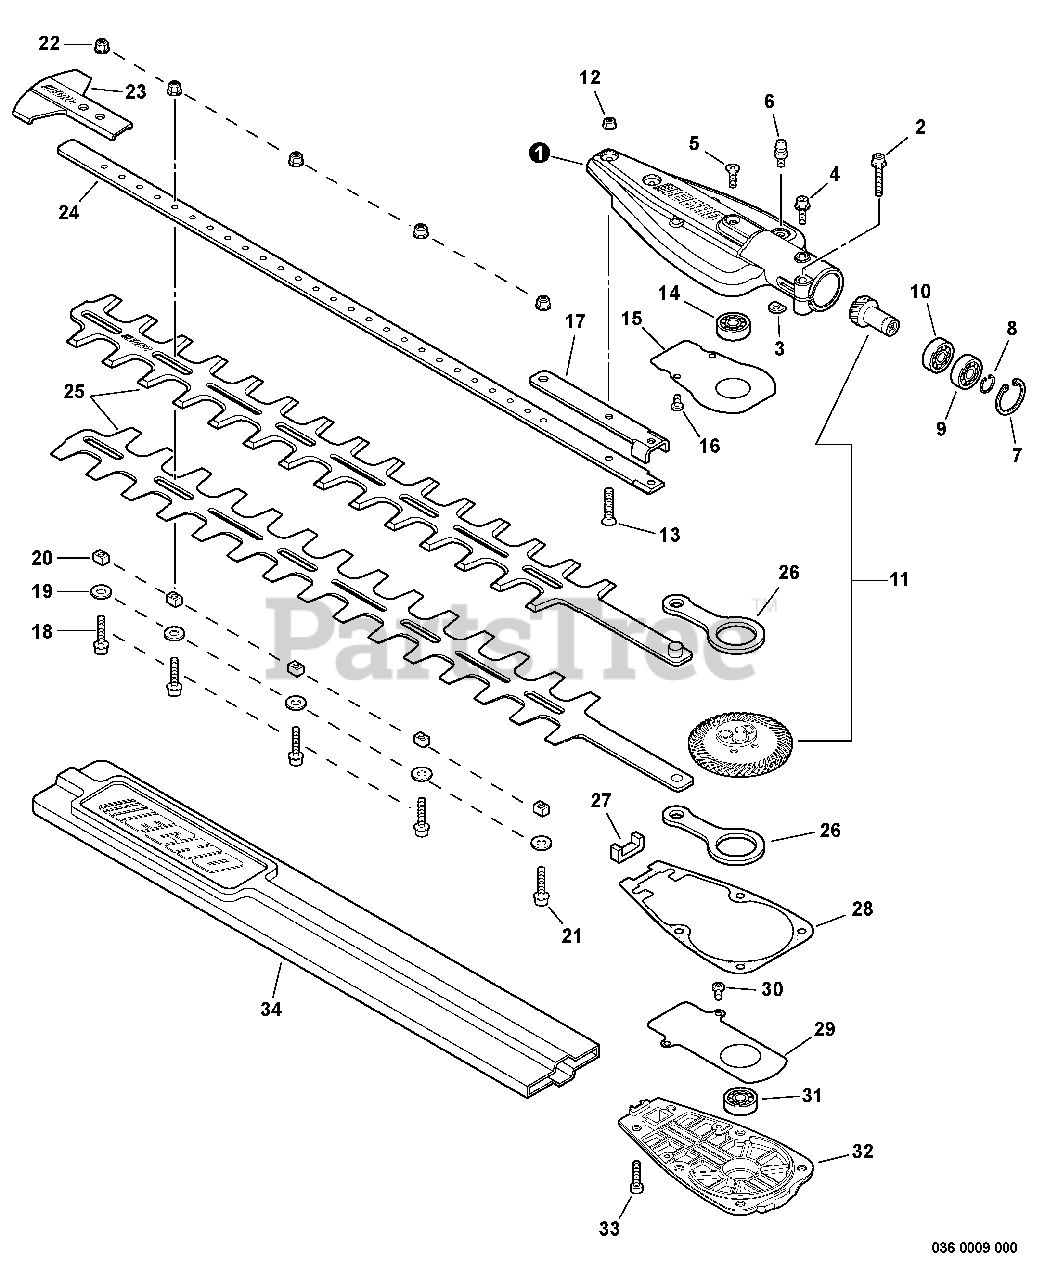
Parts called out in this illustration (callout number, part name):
1	HOUSING, GEAR CASE
2	BOLT 5×25
4	BOLT 5×12
5	SCREW 5×5/8" HD-SOCKET
6	FITTING, GREASE
7	RING, RETAINING Ø24
8	RING, SNAP Ø12
9	BEARING, BALL
10	BEARING, BALL 6901Z
11	GEAR SET
12	NUT, FLANGE M5
13	SCREW 5×18
14	BEARING, BALL 608ZZ
15	PLATE, WEAR
16	SCREW 4×5
17	SUPPORT, BLADE
18	BOLT 5×20
19	WASHER 5
20	GUIDE, BLADE 5
21	BOLT, FLANGE 5×22
22	NUT, FLANGE M5
23	GUARD, TIP
24	SUPPORT, BLADE
25	CUTTER
26	ROD, CONNECTING
28	GASKET, GEAR CASE
29	PLATE, WEAR
30	SCREW 4×5
31	BEARING, BALL 628ZZ
32	COVER, GEAR CASE
33	BOLT 5×12
34	SCABBARD
